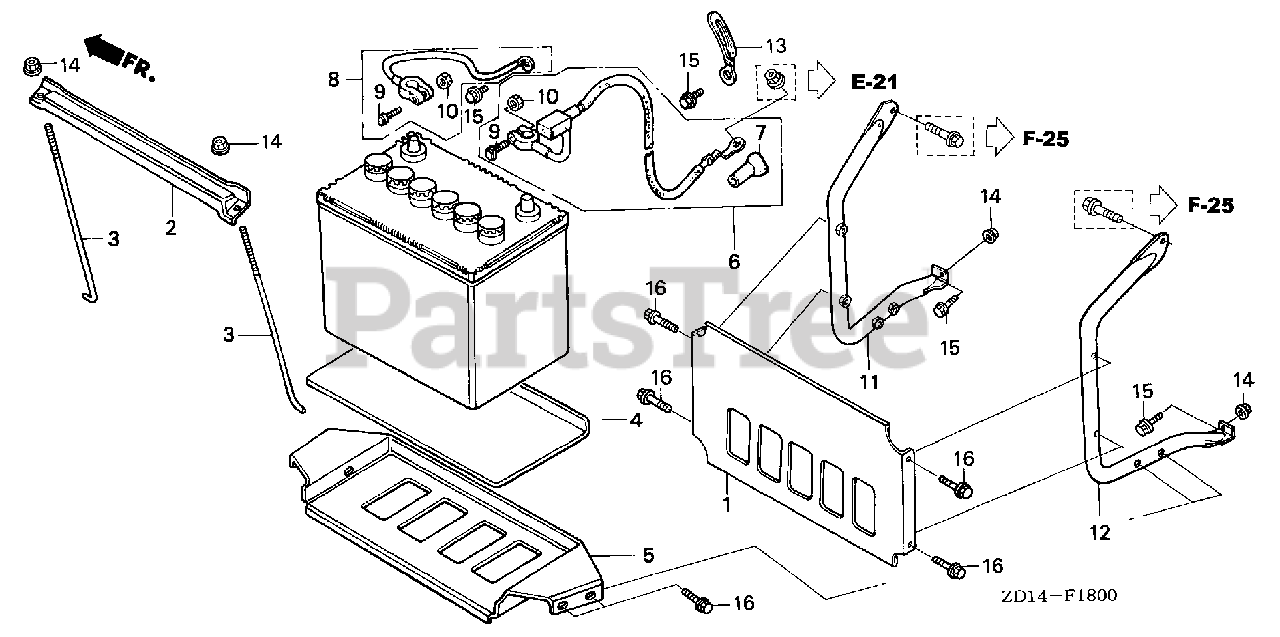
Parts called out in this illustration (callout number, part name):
1	PLATE, BATTERY GUARD
2	PLATE, BATTERY SETTING
3	BOLT, BATTERY SETTING (220MM)
4	PLATE, BATTERY
5	BASE, BATTERY TRAY
6	CABLE ASSY., STARTING
7	COVER, STARTER MOTOR TERMINAL
8	CABLE ASSY., GROUND
9	BOLT, BATTERY TERMINAL
10	NUT, BATTERY TERMINAL
11	GUARD, FR. BATTERY *NH105* (MAT BLACK)
12	GUARD, RR. BATTERY *NH105* (MAT BLACK)
13	CLIP, HEAD
14	NUT, FLANGE (6MM)
15	BOLT, FLANGE (6X12)
16	BOLT, FLANGE (6X28)
NI	BATTERY (GR.51)
